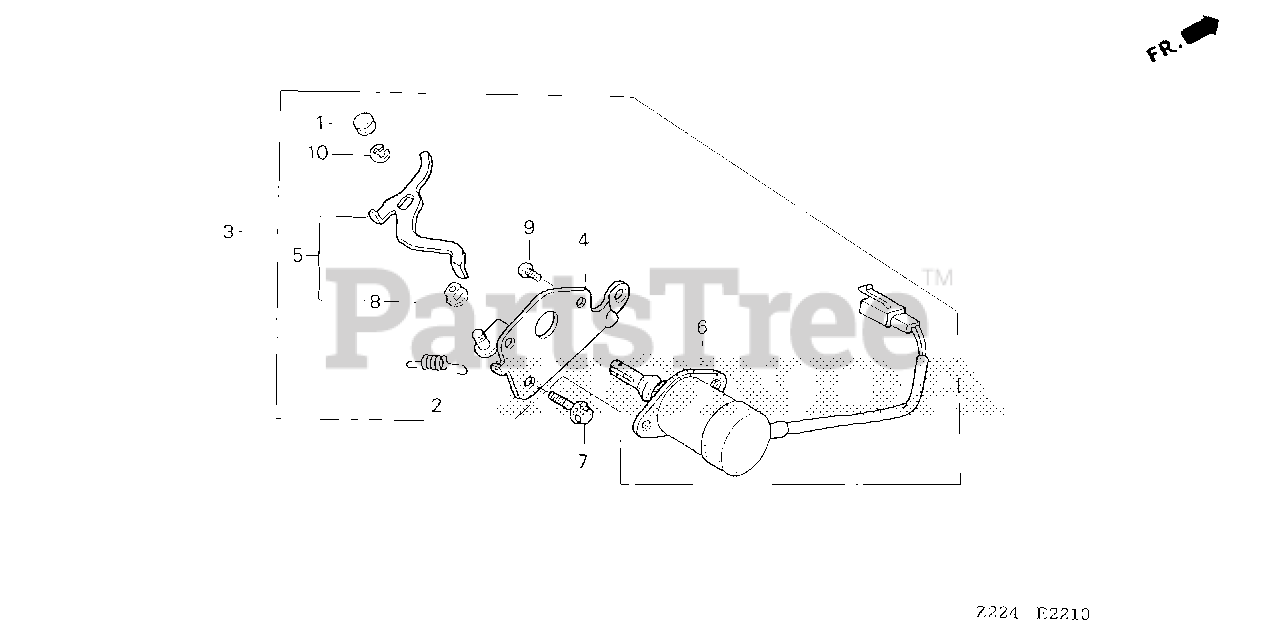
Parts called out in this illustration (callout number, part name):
1	CAP, CHOKE LEVER
2	SPRING, CHOKE RETURN
3	AUTO-THROTTLE ASSY.
4	STAY, SOLENOID THROTTLE
5	LEVER, SOLENOID THROTTLE
6	SOLENOID ASSY.
7	BOLT, FLANGE (6X12) (CT200)
8	BUSH, AUTO-THROTTLE LEVER
9	SCREW, PAN (5X8)
10	E-RING (4MM)
